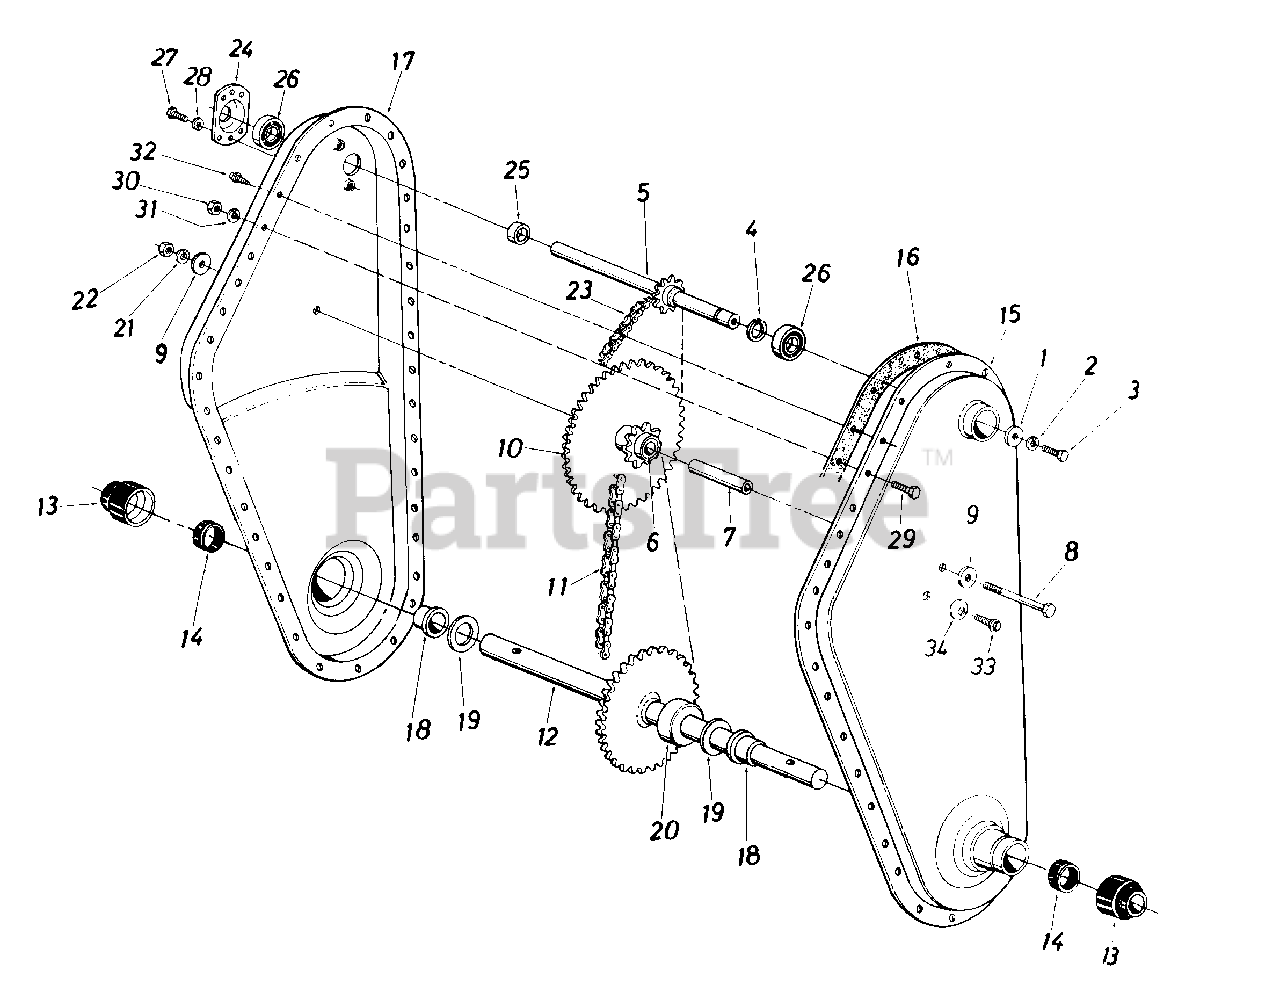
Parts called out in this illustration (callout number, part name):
1	Fl-Wash. 1/4" I.D. x .93" O.D.
2	L-Wash. 1/4" I.D.
3	Hex Bolt 1/4-28 x .62" Lg. w/Patch
4	External Snap Ring - 5/8" Dia.
5	Input Shaft Ass'y.
6	Bearing 5/8" I.D. x 3/4" O.D. x 1.860" Lg.
7	Sprocket Hub Tubing 3/8" I.D. x 5/8" O.D. x 1.90
8	Hex Bolt 3/8-24 x 2.75" Lg.
9	Fl-Wash. 3/8" I.D. x 1.25"
10	Sprocket Ass'y.
11	#50 Chain 5/8" Pitch x 46 Links Endless
12	Tine Shaft Ass'y.
13	Dust Cup
14	Seal Ring Single Lip
19	Fl-Thrust Wash. 1.0" I.D. x .03 Thk.
20	Step Spacer
21	L-Wash. 3/8" I.D.
22	Hex Nut 3/8-24 Thd.
23	#35 Chain 3/8" Pitch x 52 Links Endless
24	Bearing Housing 1.38" I.D.
25	Spacer
26	Ball Bearing .625" I.D. x 1.38" O.D. x .437
27	Hex Wash. SF-Tap Scr. 1/4-20 x .50" Lg.
28	L-Wash. 1/4" I.D.
29	Hex Bolt 5/16-18 x .75" Lg.
30	Hex Nut 5/16-18 Thd.
31	L-Wash. 5/16" I.D.
32	Hex Wash. SF-Tap Scr. 1/4-20 x .50" Lg.
33	Hex Wash. Hd. Tap Scr. 1/4-20 x .38" Lg.
34	Bell-Wash . .265" I.D. x .75"
